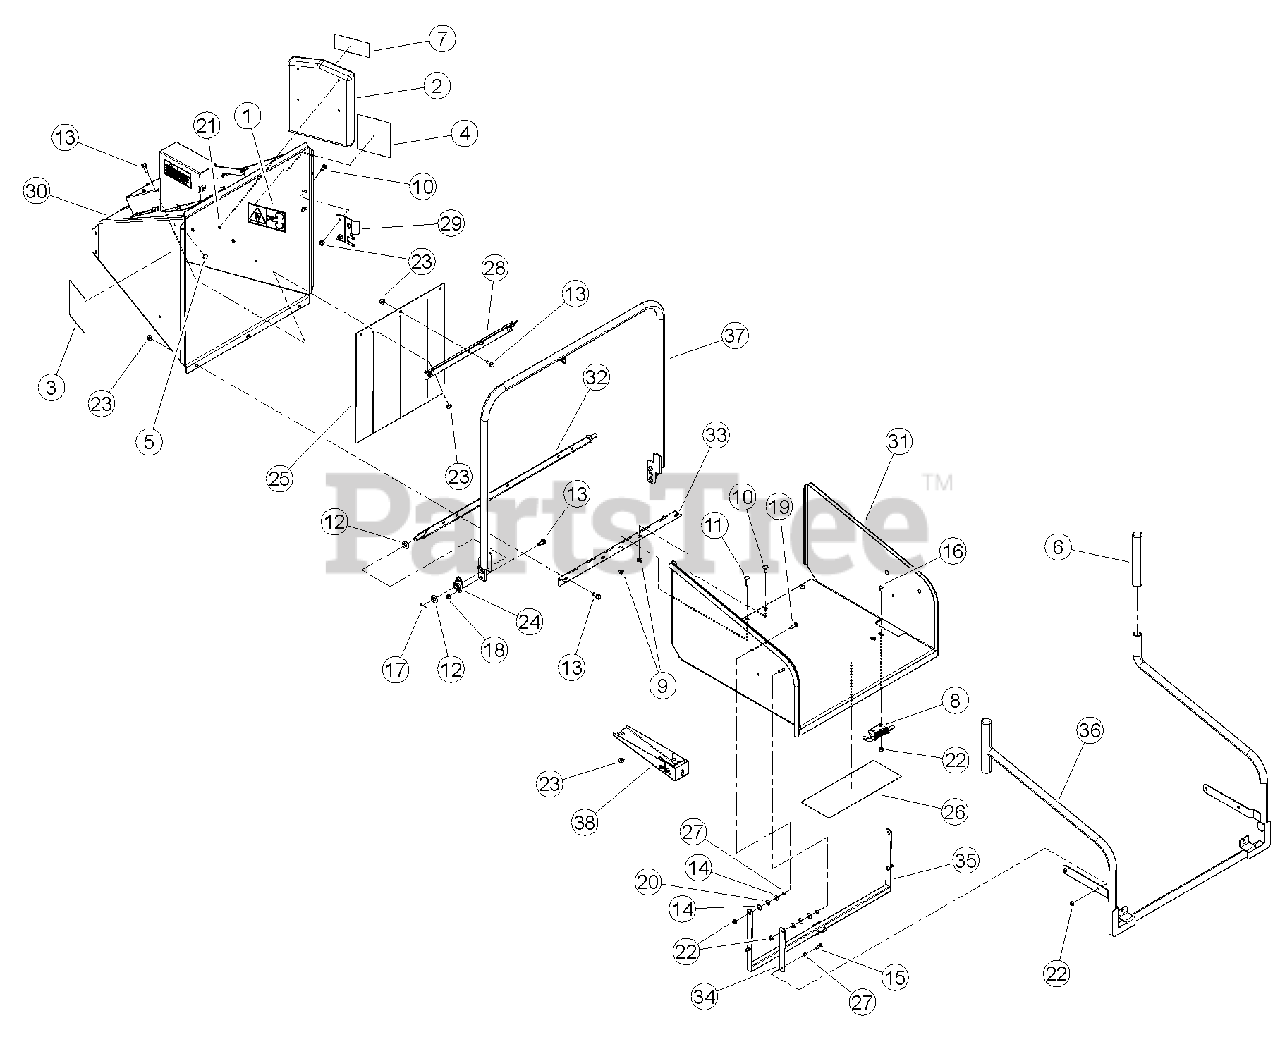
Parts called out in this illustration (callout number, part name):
1	DECAL, BLADE DANGER ISO
2	CONTAINER, INSTR. MANUAL
3	DECAL, FEED POSITION
4	DECAL, FEED POSITION
5	BUMPER, RUBBER
6	GRIP, 1.219 X 10.00
7	DECAL, MULTILINGUAL MANUAL
8	LATCH, RH HINGE
9	NUT, 3/8" SERRATED FLANGE NC ZP
10	BOLT, 3/8 X 1" GR5 CRG NC ZP
11	BOLT, 3/8 X 1-1/2" GR5 CRG NC ZP
12	WASHER, 5/8" SAE FLAT ZP
13	BOLT, 3/8 X 1 FLANGE NC
14	WASHER, 5/16" FLAT ZP
15	BOLT, 5/16 X 1" GR5 CRG ZP
16	BOLT, 5/16 X 3/4 GR5 NC ZP CRG
17	PIN, 1/8 X 1.00 ZP COTTER
18	NUT, 3/8" NE NYLOCK ZP
19	BOLT, 5/16 X 1-1/4" GR5 ZP CRG
20	WASHER, 5/16" ID 7/8" OD NYLON FLAT
21	RIVET, AL BLIND 1/4 X 1/2 DOME HEAD
22	NUT, 5/16-18 NYLOCK-FLANGE
23	NUT, 3/8-16 NYLOCK FLANGE
24	BEARING, SIDE FLANGE MOUNT 5/8"
25	FLAP, 5 INCH CHUTE
26	DECAL, BEARCAT WEB
27	SPACER, IDLER PIVOT
28	SUPPORT, 5 INCH CHIPPER FLAP
29	PLATE, TRAY STOP
30	WELDMENT, 5" CHIPPER CHUTE
31	WELDMENT, 5" XE TRAY
32	WELDMENT, CONTROL PIVOT
33	HINGE, EXTENSION TRAY
34	LINK, PARALLEL
35	WELDMENT, PIVOT TUBE
36	WELDMENT, SAFETY BAR
37	WELDMENT, CONTROL ARM
38	SHIELD, SAFETYBAR SWITCH
